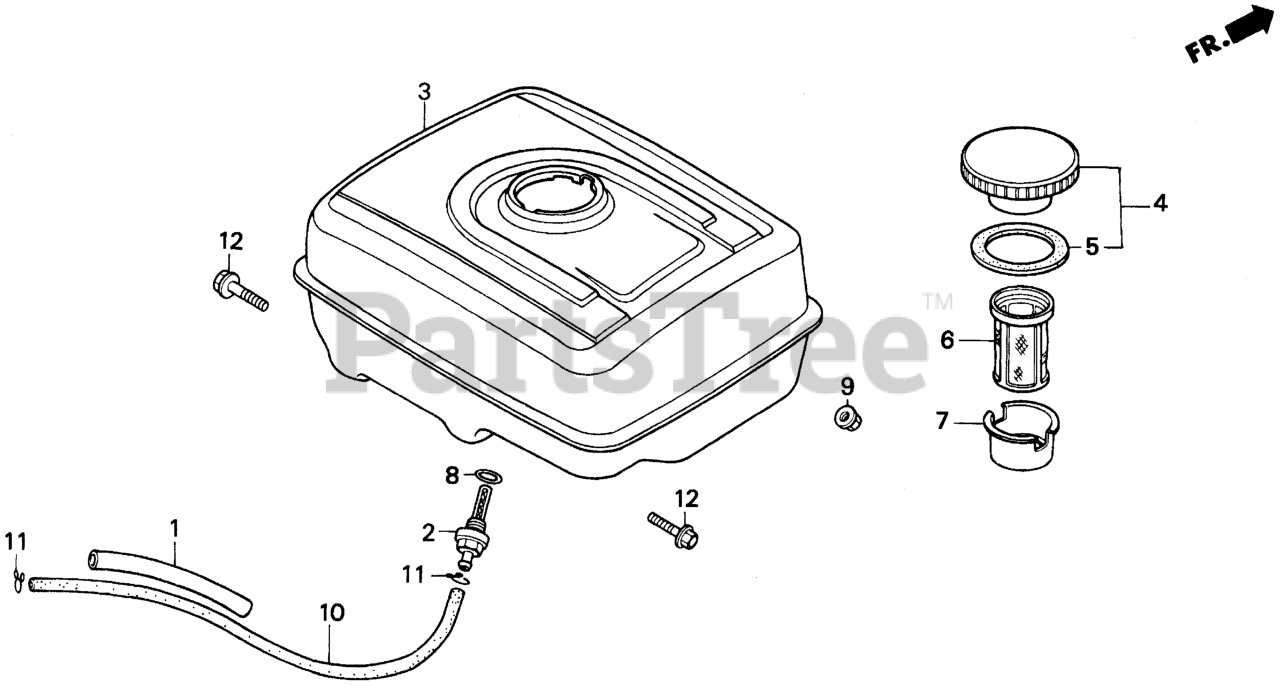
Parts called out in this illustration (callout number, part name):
1	RUBBER, SUPPORTER (107MM)
2	JOINT, FUEL TANK
3	TANK, FUEL *NH31* (MCKINLEY WHITE)
4	CAP, FUEL FILLER (BLACK) Use up to Engine SN 2115700.
4	CAP, FUEL FILLER (CHROME PLATED)
5	GASKET, FUEL FILLER CAP (39X58X3) (NOT AVAILABLE)
5	GASKET, FUEL FILLER CAP Use from Engine SN 1543258.
5	GASKET, FUEL FILLER CAP (39X58X3)
6	FILTER, FUEL Use from Engine SN 1370795.
7	HOLDER, FUEL FILTER
8	O-RING (14MM) (ARAI) Use up to Engine SN 2949254.
9	NUT, FLANGE (8MM)
10	BULK HOSE, FUEL (4.5X3000) (Honda Code 5137104). (4.5X140)
11	CLIP, TUBE (B8)
12	BOLT, FLANGE (8X25)
